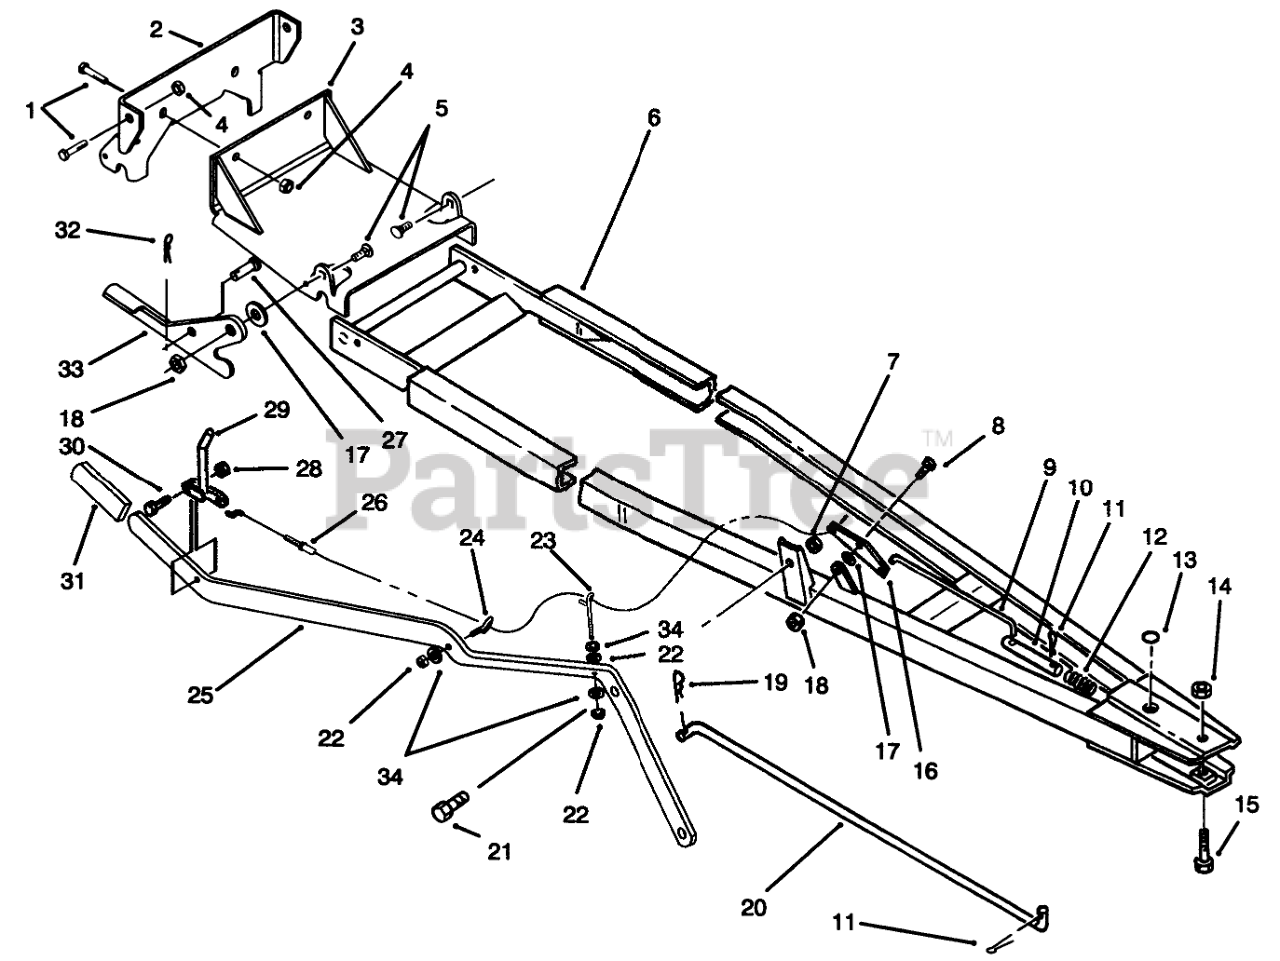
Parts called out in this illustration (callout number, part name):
1	SCREW-HH
2	BRACKET-MOUNTING
3	BRKT - BLDE MTG WA BLACK
4	NUT-LOCK, NI
5	BOLT-CARR
6	FRAME-BLADE
7	NUT-JAM
8	SCREW-HH
9	ROD-LOWER INDEX
10	PIN-INDEX
11	PIN-COTTER
12	SPRING-COMPRESSION
13	PLUG
14	Nut
15	SCREW-HH
16	PLATE - INDEX
17	WASHER-FLAT
18	NUT-LOCK, NI
19	Hairpin
21	SCREW-HH
22	NUT-LOCK, NI
23	EYELET - CABLE
24	EYEBOLT
25	LEVER - INDEX BLADE
26	Cable-Lift
27	Pin
28	NUT-LOCK
29	LEVER-INDEX
30	SCREW-HH
31	GRIP
32	Hairpin
33	PLATE-LATCHING
34	WASHER-FLAT
